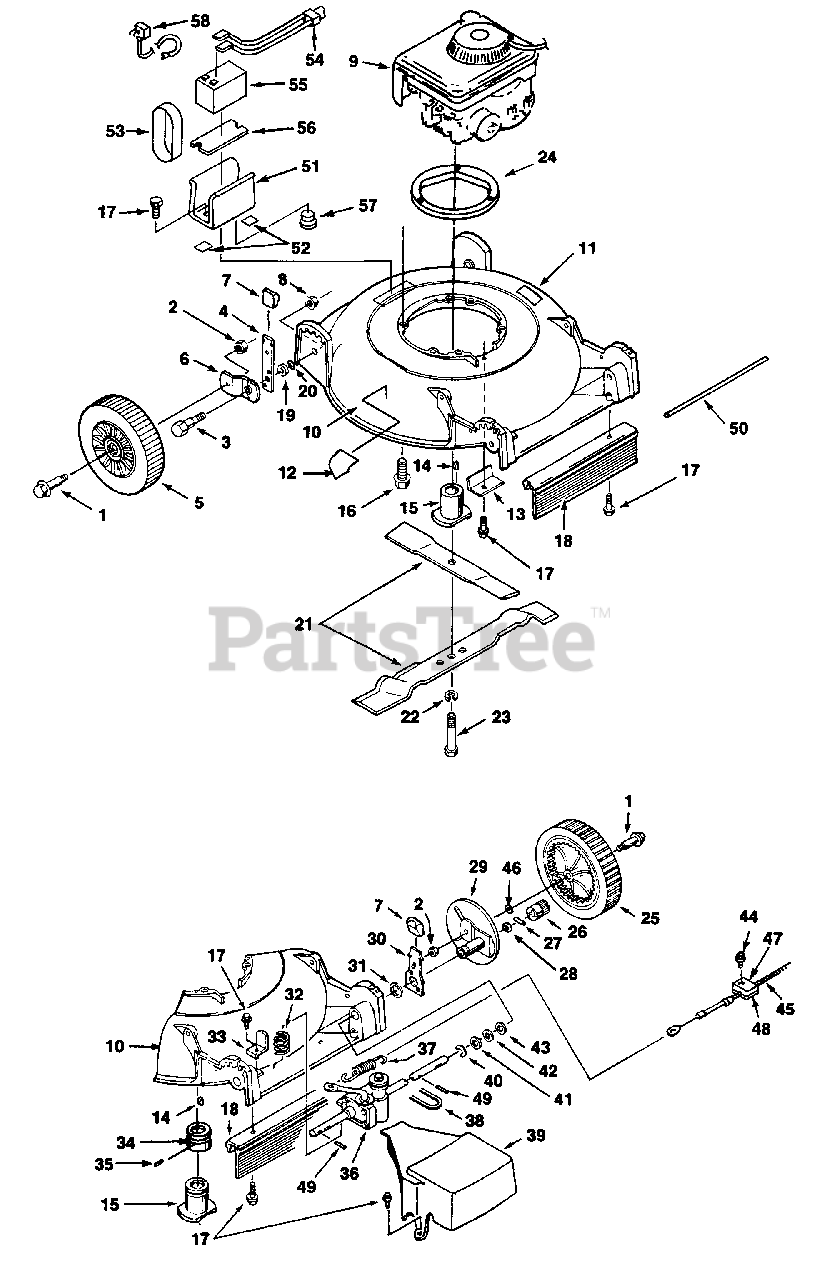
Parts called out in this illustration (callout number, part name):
1	SUPPORT- Axle
2	NUT
3	BOLT- Height adjusting
4	INDEX SPRING & PIN
5	WHEEL & TIRE
6	ARM- Wheel adjusting
7	KNOB- index spring
8	NUT- Flange
9	ENGINE
10	DECK- 20"
11	DECAL- Warning
12	DECAL- CPSC
13	COVER- Belt opening
14	KEY- Woodruff
15	ADAPTOR- Blade
16	SCREW- (3/8-16 x 1 1/2")
17	SCREW- (3/8-16 x 3/4")
18	DEFLECTOR
19	SPACER- Height adjusting
20	WASHER- Flat (5/16")
21	BLADE KIT
22	WASHER- Lock (3/8")
23	SCREW- Hex hd. (3/8-24 x 2")
24	RING- Engine
25	WHEEL & TIRE
26	PINION- R.H.
27	PIN- Drive
28	WASHER- Thrust (9/16 x 1 1/8")
29	SUPPORT- Drive wheel
30	INDEX SPRING & PIN
31	SPACER- Rear
34	PULLEY- Drive
36	REDUCER- Gear
37	SPRING- Extension
38	BELT- Traction
39	COVER- Drive
40	RING- Eaton
44	BOLT
45	TRACTION CABLE
47	CLAMP- Casing
48	PLATE- Backing
49	PIN- Roll
51	HOLDER- Battery
53	BAND- Rubber
54	LEAD- Battery
55	BATTERY- 12V
56	PAD- Battery
58	CHARGER- Battery
